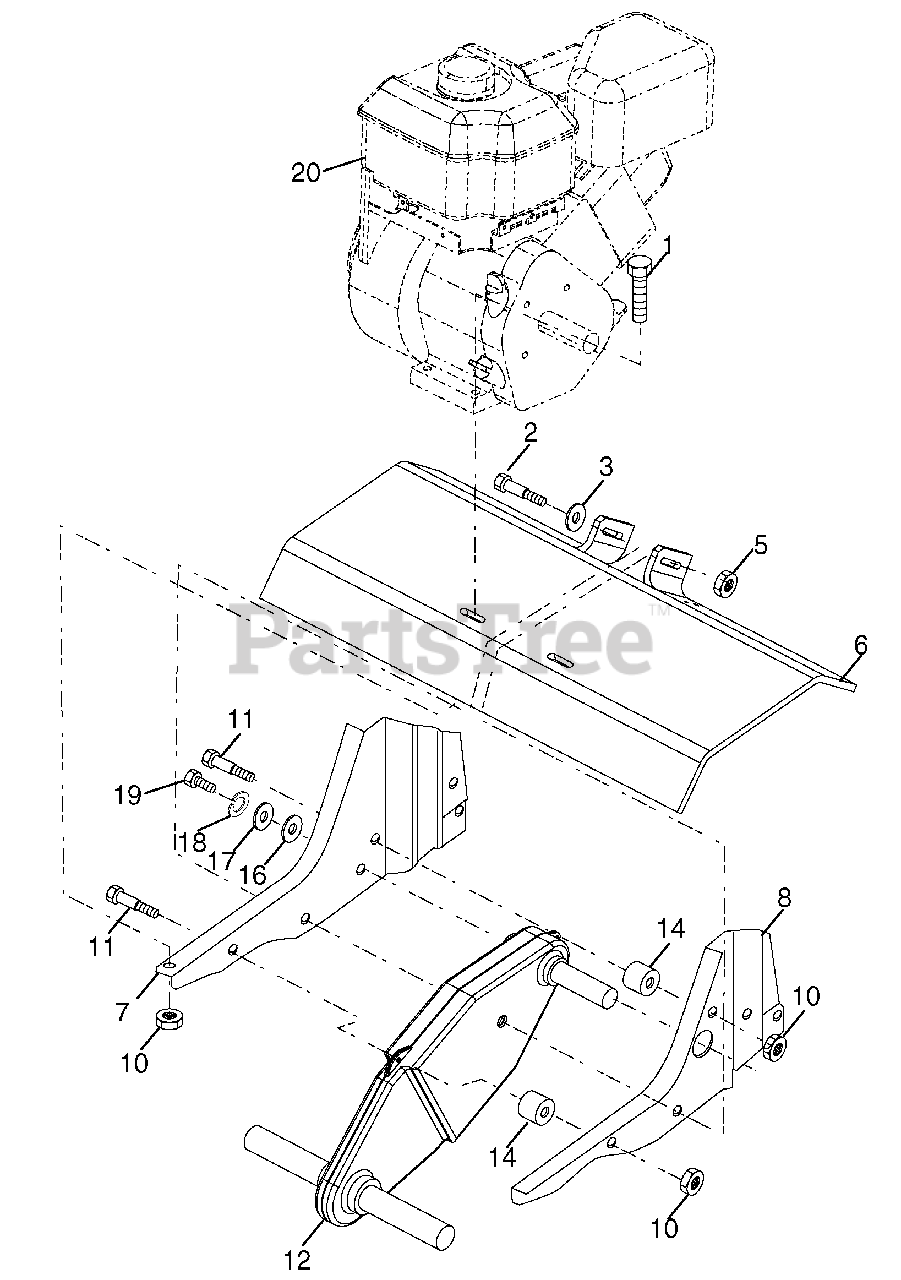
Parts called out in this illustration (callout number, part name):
1	Bolt, Hex Head, Gr. 25/16-18 x 1-1/2
2	Bolt, Hex Head, 3/8-16 x 3-1/4
3	Washer, 3/32 x 13/16 x 11
5	Nut, Hex, Flangelock 3/8-16
6	Shield, Tine
7	Bracket, Engine, R.H.
8	Bracket, Engine, L.H.
10	Nut, Hex, Flangelock
11	Bolt, Shoulder
12	Transmission
14	Spacer, Split
16	Washer, 9/32 x 7/8 x 12 Ga.
17	Washer, 9/32 x 1-1/4 x 16 Ga.
18	Washer, Lock 1/4
19	Bolt, Hex Head, Gr. 51/4-28 x 3/4
